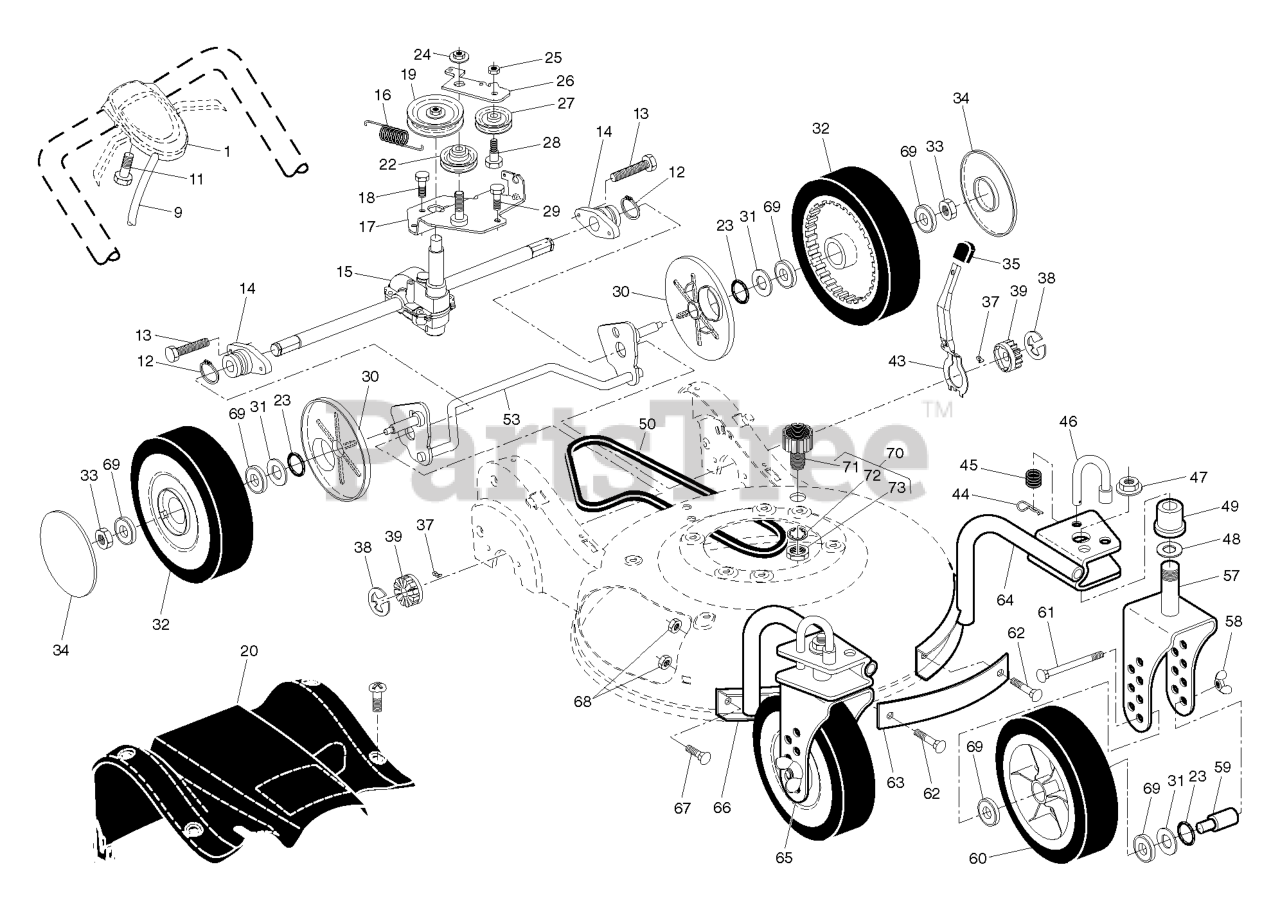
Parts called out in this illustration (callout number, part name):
1	RP CONTROL.DR.DTRIG.HV.GRY/BLK
9	DRIVE.DUAL.TRIG.HIVAC.AUTO
12	RETAINING RING (2 2)(3 2)
13	HINGE SCREW
14	BEARING / AXLE SUPPORT
15	TRANSMISSION.21.HV.RWGD.AW/EZ
17	BRACKET, GEAR CASE / DRIVE
19	RP PULLEY.DRIVE.EZ
20	COVER.DR.ASM.408006X418.CE
22	PULLEY.IDLER.V-BELT
23	O-RING
24	NUT.HEX.FLANGE.3/8-16.LOCKNUT
25	NUT.CENTERLOCK.5/16-
26	ARM.IDLER.BZP
27	IDLER PULLEY
28	SHOULDER BOLT
29	SCREW 14-20 X 5/8
30	DUST COVER, WHEEL
31	WASHER.FLAT.1/2
32	WHEEL.9X2.25.LP.TIGER.BLACK
33	NUT.HEX.FLANGE.3/8-16.LO(3 2)
34	HUBCAP.WHEEL.5.SPOKE.SILVER
35	KNOB.SELECTOR.SPRING.BLACK(3 2
37	PAWL, DRIVE
38	E-RING 7/16 RE
39	PINION.14.TEETH.FGD
43	LEVER, SELECTOR, HEIGHT, REAR
44	SPRING RETAINER
47	NUT.HEX.FLANGE.3/8-16.LOCKNUT
48	WASHER.FLAT.1/2
50	BELT, DRIVE
53	SHAFT.ASM.REAR.TORQUE.HV.BZP
57	BRACKET.WHEEL.ASM.LT.CASTER.OR
58	NUT.WING.5/16-18.YELLOW
60	WHEEL.9X2.25.LP.TIGER.SILVER
61	CARRIAGE BOLT
63	STRAP.FRONT.CASTER.ORANGE
64	SUPPORT.TUBE.ASM.LT
65	BRACKET.WHEEL.ASM.RIGHT.ORANGE
66	SUPPORT.TUBE.ASM.RT
68	NUT
69	BEARING.8".WHEEL
70	KIT.WASH-OUT.PORT
71	FITTING, HOSE, WATER WASHOUT
72	WASHER.LOCK.INTERNAL.TOOTH
73	LOCKNUT.HEX.WITH.O-RING
